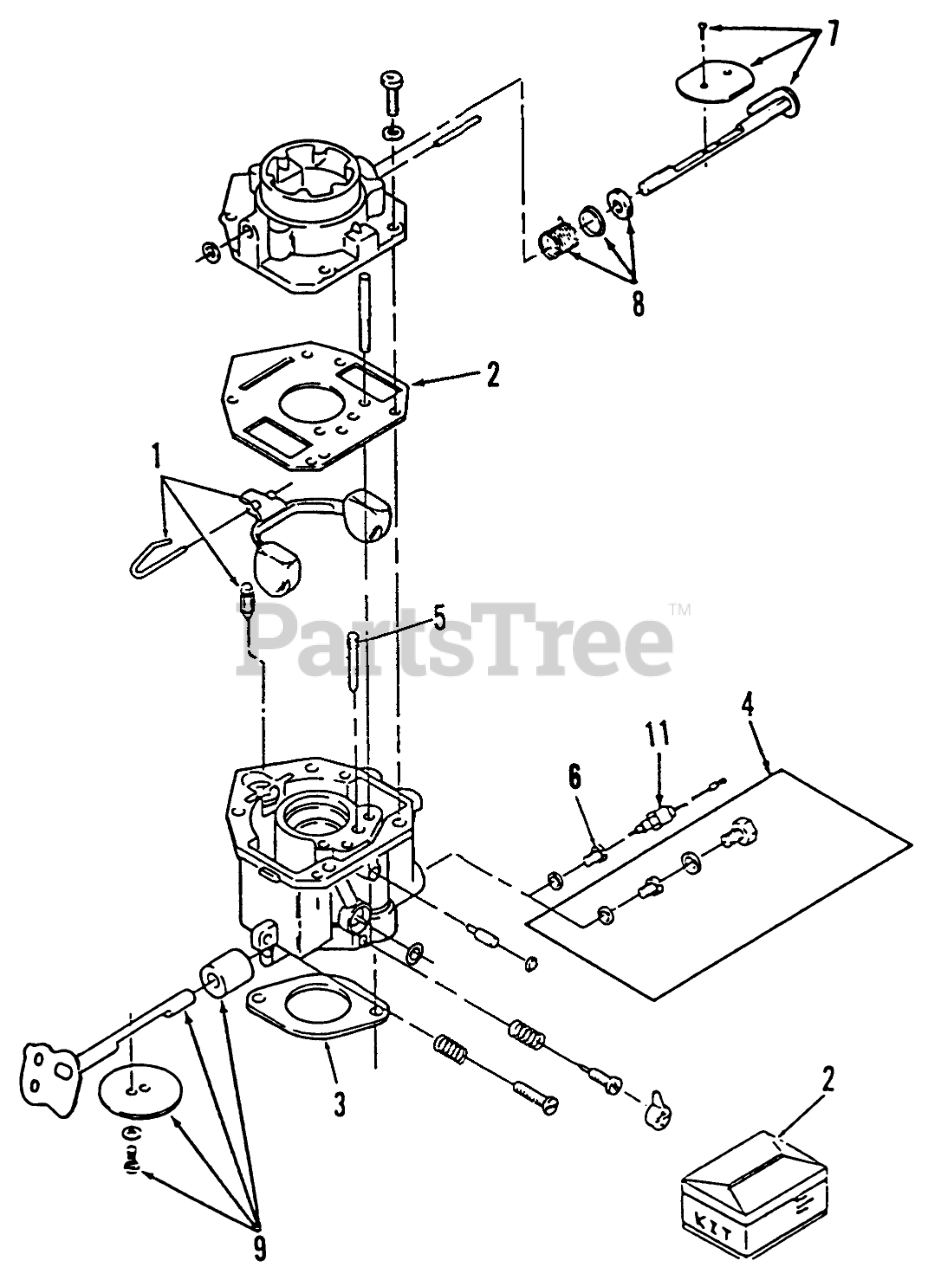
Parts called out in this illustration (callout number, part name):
1	Float Kit (Includes Float, Pin and Valve)
2	Repair Kit (Includes Screw and Plug Package, Gasket Package, Float Valve, Idle Adjustment Needle and Spring, Mounting Gaskets, Idle Limit Cap)
3	Gasket
4	FIXED-JET PKG
5	Idle Jet
6	POWER JET
7	Choke Shaft Kit (Includes Choke Valve, Valve Set Screw and Air Filter)
8	Choke Lever Kit (Include Choke Lever Ring, Choke Spring and Choke Collar)
9	Throttle Shaft Kit (Includes Valve Set Screw, Air Filter and Throttle Valve)
11	Solenoid
